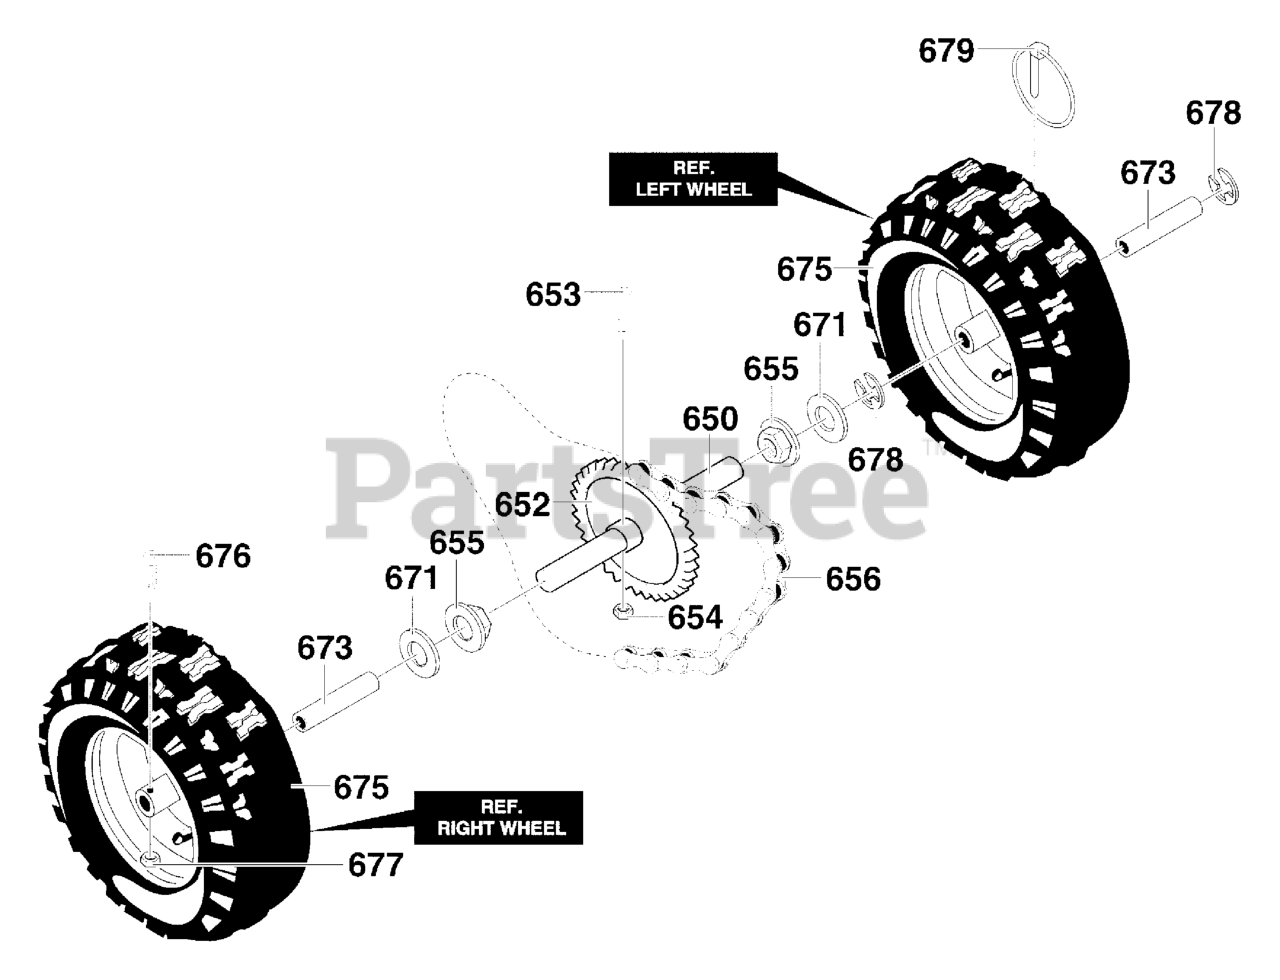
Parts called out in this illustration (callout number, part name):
650	SHAFT, AXLE
652	SPRKT & HUB
653	SCREW, 1/4-20X2.25
654	NUT, 1/4-20 HEX NYLOCK
655	BRNG, FL
656	CHAIN, ROLLER
671	FLATWASHER .765X1.12X.06
673	BUSHING, WHEEL
675	TIRE & RIM
676	SCREW, 1/4-20X1.75 HH
677	NUT, 1/4-20 HEX NYLOCK
678	RING, RET
679	PIN, KLIK .25 X 1.38 DIA
